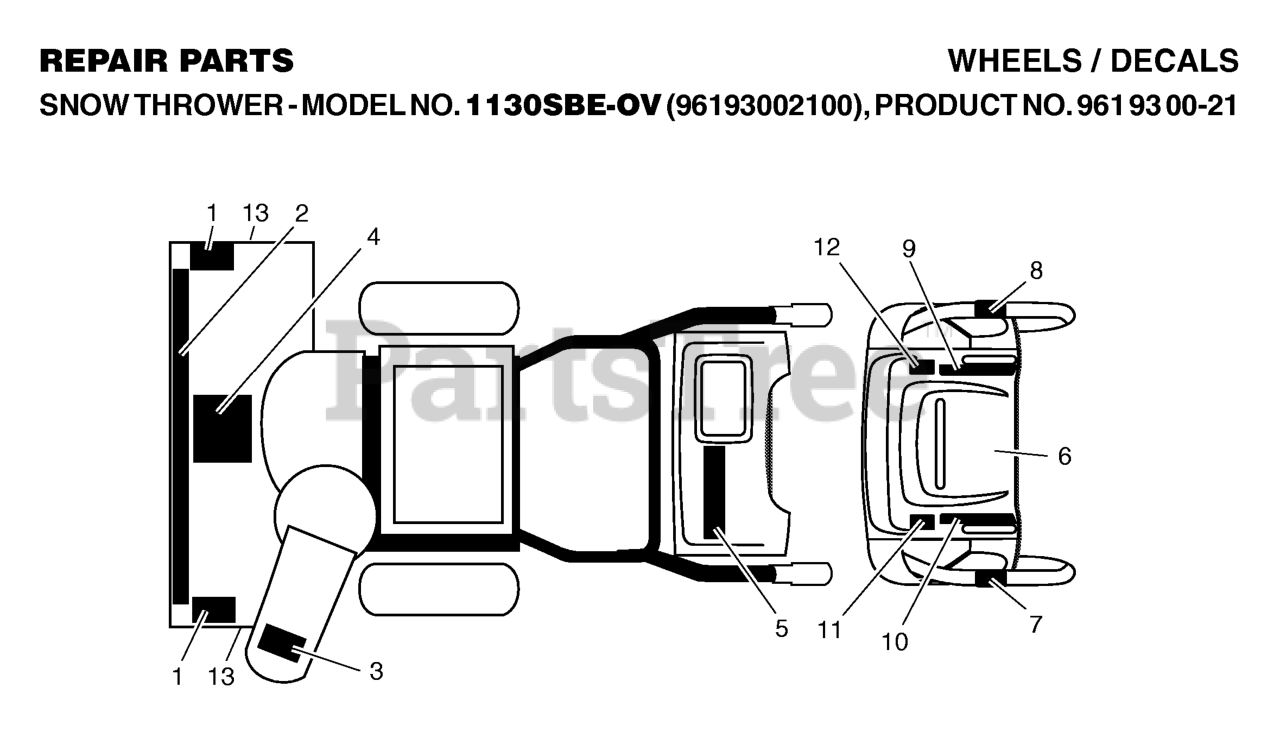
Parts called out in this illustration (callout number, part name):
1	DECAL DANGER
2	DECAL, AUGER HOUSING
3	DECAL, DANGER DEFLECTOR
4	DECAL, DANGER
5	DECAL, HUSQVARNA, 1130SBE-OV
6	DECAL.SNOWTHROWER.CONSOLE.INST
7	DECAL.TRACT.ASM.ENG.CLUTCH.K
8	DECAL, AUGER LEVER
9	DECAL, SPEED CONTROL
10	DECAL, REMOTE DEFLECTOR
11	DECAL, LH TRIGGER
12	DECAL, RH TRIGGER
13	DECAL, HUSQVARNA
